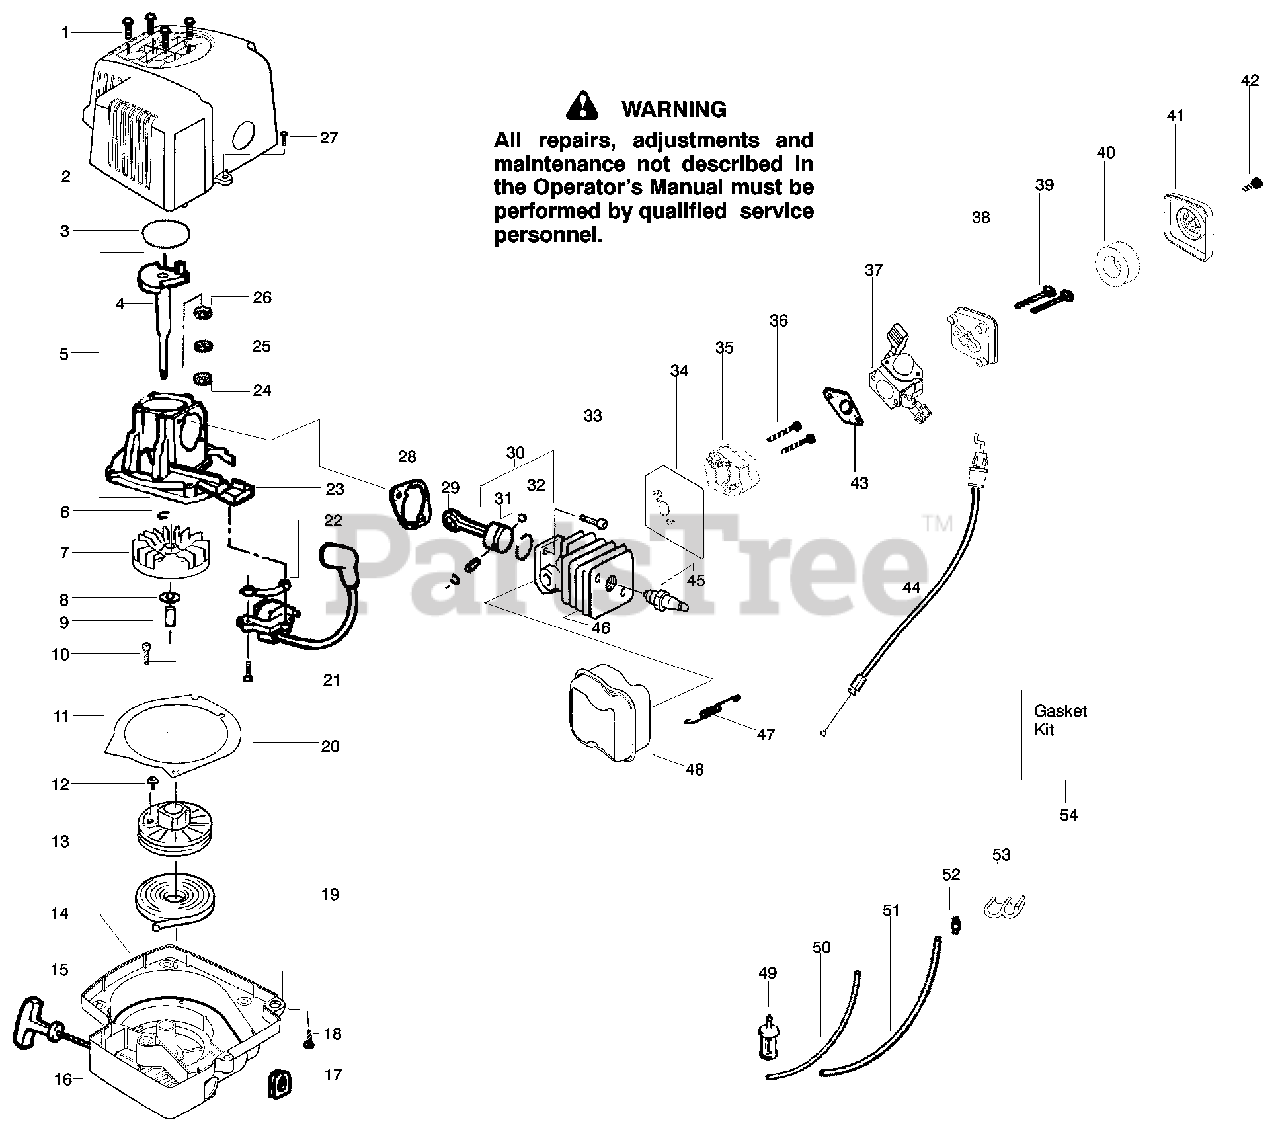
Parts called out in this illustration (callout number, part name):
2	Assy-Shroud
3	O-Ring-Shrd (kit)
4	Assy-Crankshaft
5	Assy-C/case-C/shaft
6	Ring-Retainer-C'shaft
7	Assy-Flywheel
8	Washer-Flat
9	Spacer-Flywheel
11	Plate-Baffle
13	Kit-Starter Pulley
14	Assy-Fan Housing
15	Handle-Starter
16	Kit-Rope
17	Grommet-Ignition Module
18	Screw-(f/hsg to shrd)
19	Spring-Starter
21	Ignition Module
22	Spacer-Ign. Module
23	Assy-Crankcase
24	Bearing-Outer
25	Kit-Crankcase Seal
26	Bearing-Inner
28	Gasket-Cylinder (kit)
29	Assy-Connecting Rod
30	Kit-Piston
31	Retainer-Piston Pin
32	Ring-Piston
34	Gasket-Carb. Adapt.(kit)
35	Adapter-Carburetor
37	Kit-Carburetor Ass'y. (C1U-W13)
37	Kit-Carburetor Ass'y. (C1U-W13A)
40	Air Filter Foam
41	Air Filter Cover
43	Gasket-Carburetor (kit)
44	Assy-Throttle Cable
45	Spark Plug(RCJ-6Y)
46	Kit-Cylinder
47	Spring-Muffler
48	Kit-Spark Muffler
49	Assy-Pick-up
50	Kit-Fuel Line(small)
51	Kit-Fuel Line(large)
52	Fitting-Fuel Line
53	Clip-Retainer
54	Kit-Gasket
